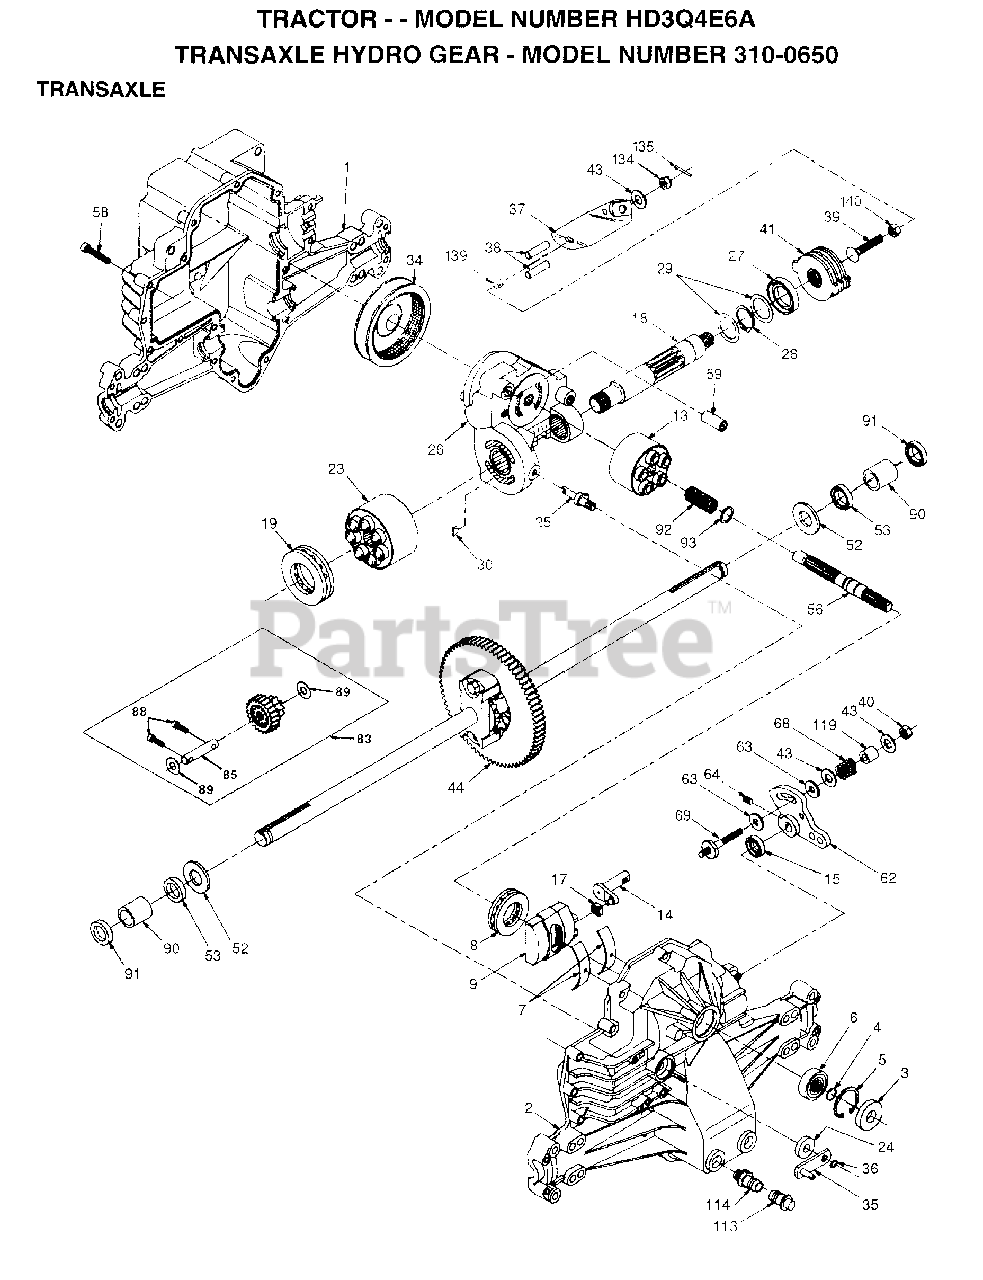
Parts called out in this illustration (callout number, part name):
1	HOUSING.L.50074RM
2	HOUSING.UP.70125
3	SEAL.9008000-0128
4	RING.RET.2003016.
5	RING.RET.2003052.
6	BEARING.(50552)42X68X16
7	CRADLE- 2003023.
8	BEARING.THU.50551
9	SWASHPLT.2003087.
13	BLOCK.CLYN.70079.
14	ARM.TRUN.2003005.
15	SEAL.9008000-0126
17	GUIDE.2000015.
18	SHAFT.MOTOR.50449
19	BEARING.THU.50552
23	BLOCK.CYLIN.70082
24	SEAL.LIP.45074
25	ACTUATOR.2003555
26	KIT.CEN.SEC.70250
27	SEAL.LIP.45075
28	RING RETAIN 50007
29	WASHER.44872
29	PIN.HYDRO.50002
34	ELEMENT.OIL.44964
35	ARM.BYPASS.50270
36	RING.RETAIN.44870
37	ARM.ACTUAT.23710
38	PIN.ACTUAT.44891
39	BOLT.50316
40	NUT.LOCK.HX.50317
41	KIT.BRAKE.70135
43	WASHER HYD 44130
44	DIFFRENTIAL.70226
52	WASHER.HYD.44875
53	SEAL.HYDRO.45076
56	SHAFT.INPUT.50005
58	BOLT.1/4-20.44876
62	ARM.CONTROL.50254
63	PUCK.DAMPER.50281
64	SCREW.SET.50018.
68	SPRING.HYD.50277
69	STUD.5/16-24.DANA
83	JACKSHAFT/PINION GEAR.70132
83	SPRING.2003014.
85	PIN.SHAFT 50559
88	SCREW.CAP.50154.
89	WASHER.HYD.50132
90	BEARING.SLV.50118
91	SEAL.WIPER.50941
93	WASHER.2003017
113	CAP.VENT.70109
114	CAP.VENT.70109
119	SPACER.HYD.50278
134	NUT.CAS.HYD.44142
135	PIN.COT.HYD.44101
139	SPRING.COMP.50431
140	NUT.HEX.50269
